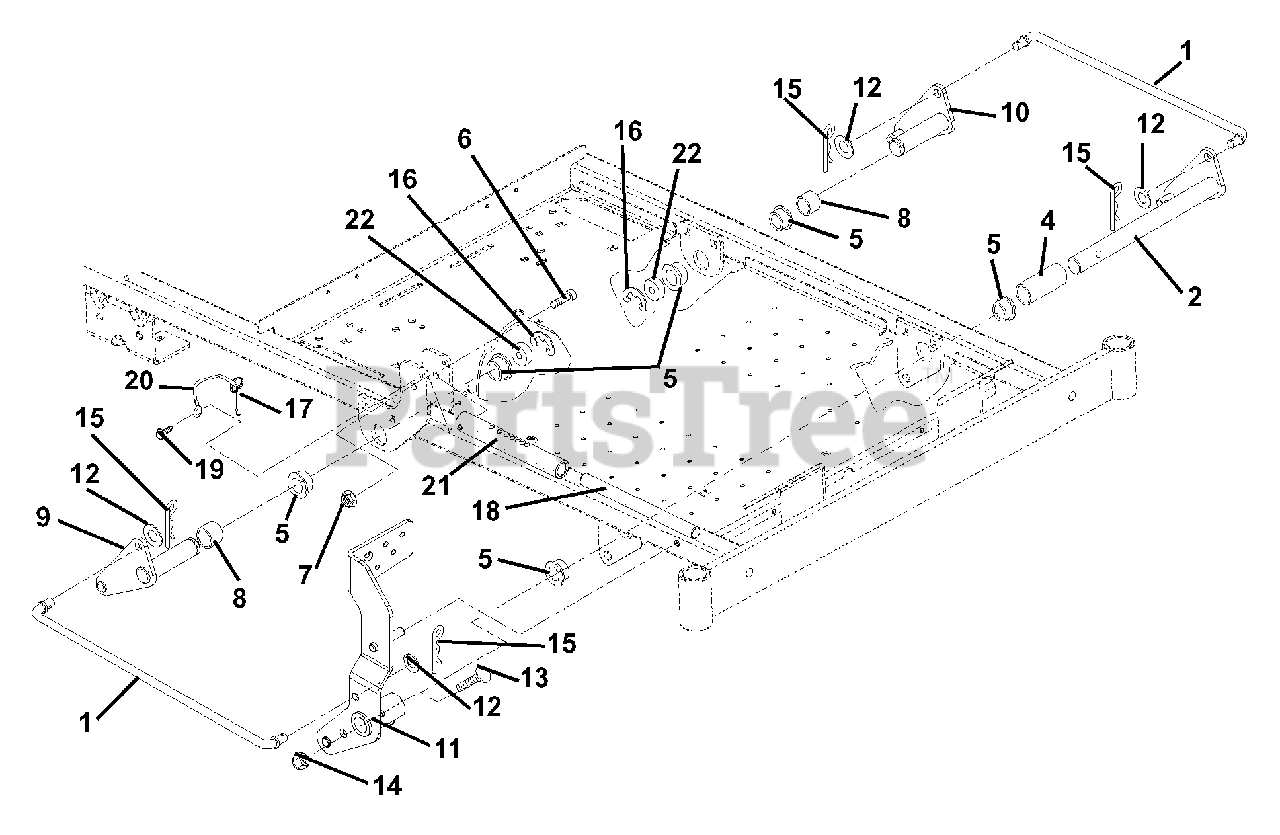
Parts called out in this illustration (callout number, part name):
1	ROD, LIFT
2	WELDMENT,FRONT LIFT
3	TRUNNION-.50
4	BSHG, SPCR 1.01X1.25X2.63 PM
5	BSHG-FLG 1.000X1.12X.62X1.50BR
6	BLT, SKH SHLD .31X18X2.00
7	@NUT-LK-NYL-FLG .31-18 YWZC
8	BSHG-SPCR 1.032X1.250X.88 PM
9	WELDMENT, LIFT, REAR - RH
10	WELDMENT, LIFT, REAR - LH
11	WMT, FOOT PEDAL
12	@WSHR-FL-STL.531X1.06X.095YWZC
13	@BLT-HEX .38-16X2.00 GR5 YWZC
14	@NUT-LK-NYL-FLG .38-16 YWZC
15	PIN, HAIR, EXT - #16 YWZC
16	RG-RTNG .822X1.500X.050 TYP E
17	PIN, SPRING BALL .375OD X 1.50
18	ROD, LIFT
19	@SCR-TAP .25-20X.37 HWH YWZ TR
20	CBL,HOOD
21	TUBE, LIFT STOP
22	BSHG, SPCR 1.032X1.25X.25 PM
